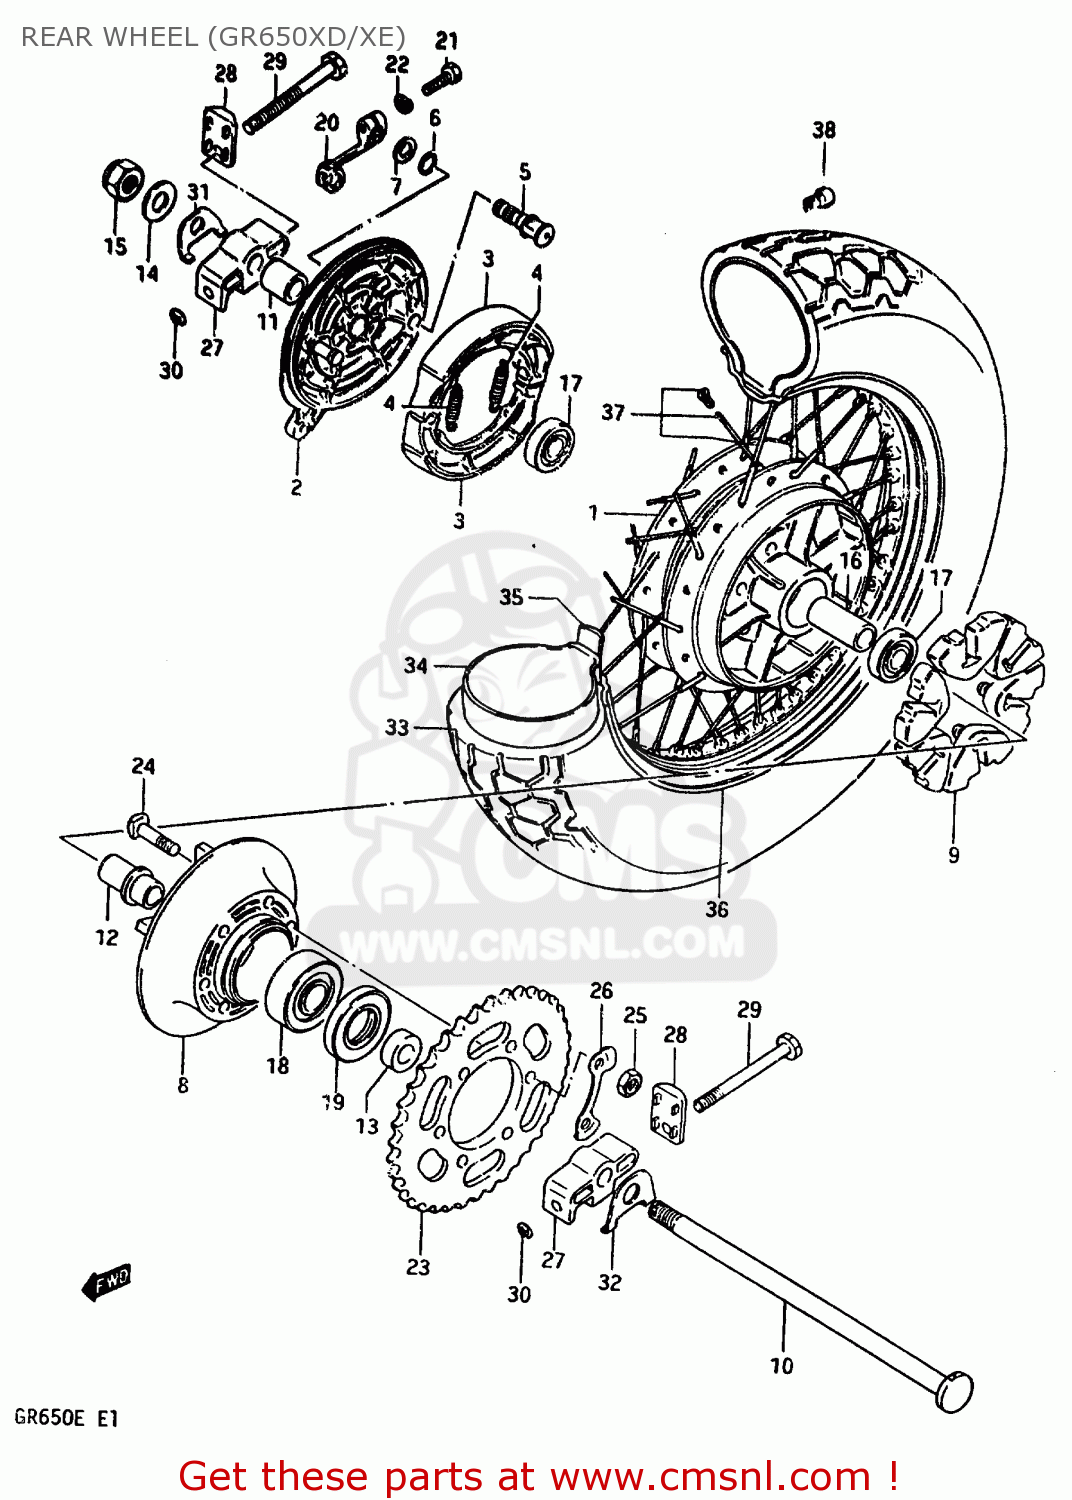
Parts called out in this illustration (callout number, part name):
1	DRUM,REAR HUB
2	PANEL,REAR HUB
3	SHOE,BRAKE
4	SPRING,BRAKE SHOE
5	CAM,FRONT BRAKE
6	O-RING,BOSS
7	WASHER (15X24X1.6)
8	DRUM,REAR SPROCKET MOUNT
9	ABSORBER,REAR HUB SHOCK
10	AXLE,REAR
11	SPACER (17.5X28X35)
12	RETAINER,RR SPROCKET DRUM
13	SPACER (17X33X12.5)
14	WASHER (17X30X3.2)
15	NUT
16	SPACER(17.5X25X70)
17	BEARING
18	BEARING
19	SEAL,OIL(33X62X7)
20	LEVER,REAR BRAKE CAM
21	BOLT
22	LOCK WASHER
23	SPROCKET,REAR
24	BOLT
25	NUT
26	WASHER
27	BODY,CHAIN ADJUSTER
28	PLATE,CHAIN ADJUSTER
29	BOLT,CHAIN ADJUSTER
30	E RING
31	WASHER,CHAIN ADJUSTER
32	WASHER,CHAIN ADJUSTER
33	TIRE,REAR
34	TUBE ASSEMBLY,WHEEL,INNER
35	PROTECTOR,INNER TUBE
36	RIM,REAR WHEEL (2.50X16)(
37	SPOKE SET,REAR
38	BALANCER,WHEEL (B)
